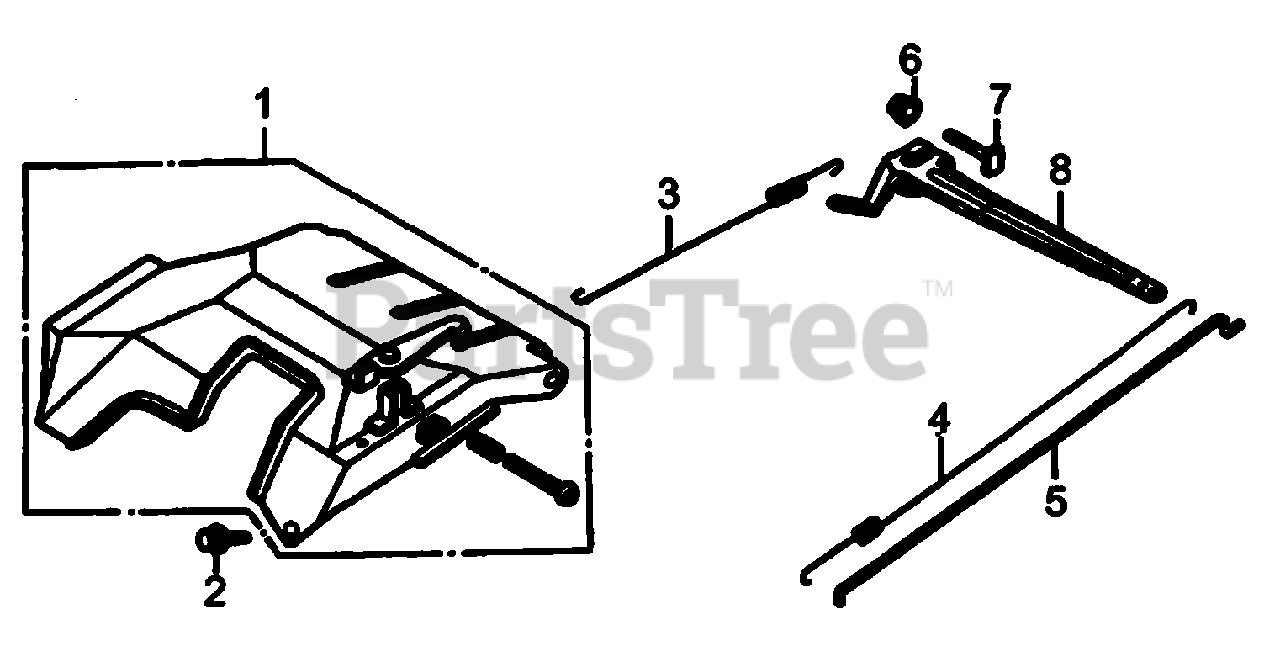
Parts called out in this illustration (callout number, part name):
1	CONTROL ASSY.
2	NUT, FLANGE M6
3	SPRING, CABLE RETURN
4	SPRING, THROTTLE RETURN
5	ROD, GOVERNOR
6	NUT, FLANGE M6
7	BOLT, QUADRATE HEAD
8	ARM, GOVERNOR
